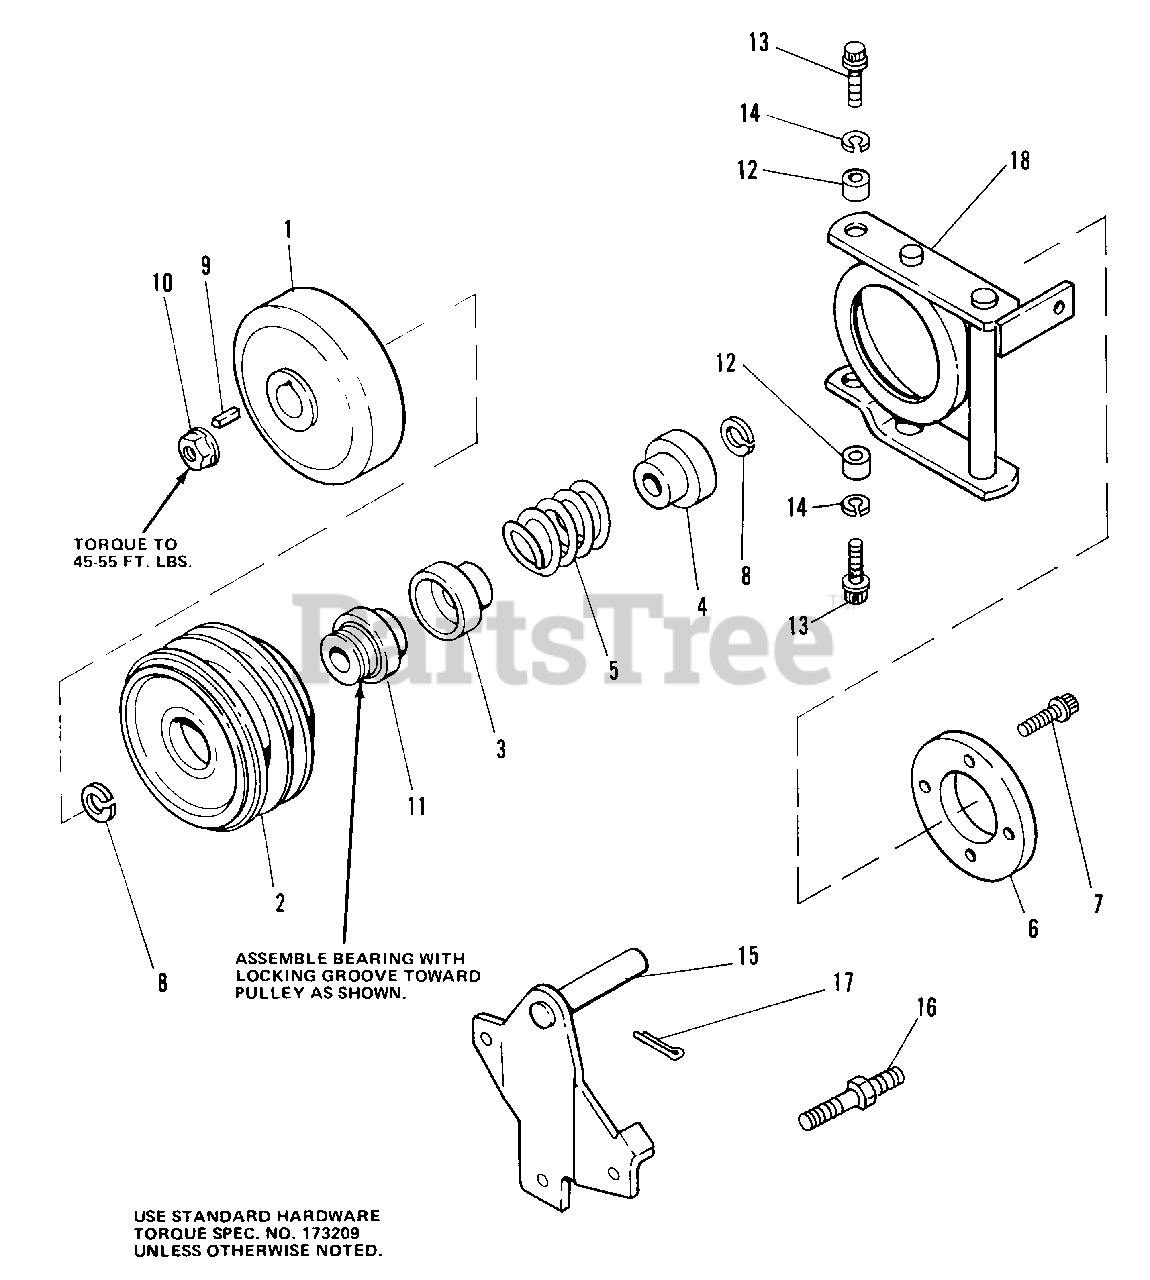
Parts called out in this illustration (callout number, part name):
1	CLUTCH PLATE ASSEMBLY
3	GUIDE, Spring
4	GUIDE, Spring
6	DISC, Brake
7	CAPSCREW, Skt. Hd., 1/4-20 x 5/8
8	RING, Retaining
10	LOCKNUT, Flange, 1/2-13
11	BEARING ASSEMBLY
13	SCREW, Thd. Forming
14	LOCKWASHER, 5/16
15	PIVOT ARM ASSEMBLY
17	PIN, Cotter, 3/16 x 1-1/2
18	PIVOT ASSEMBLY
